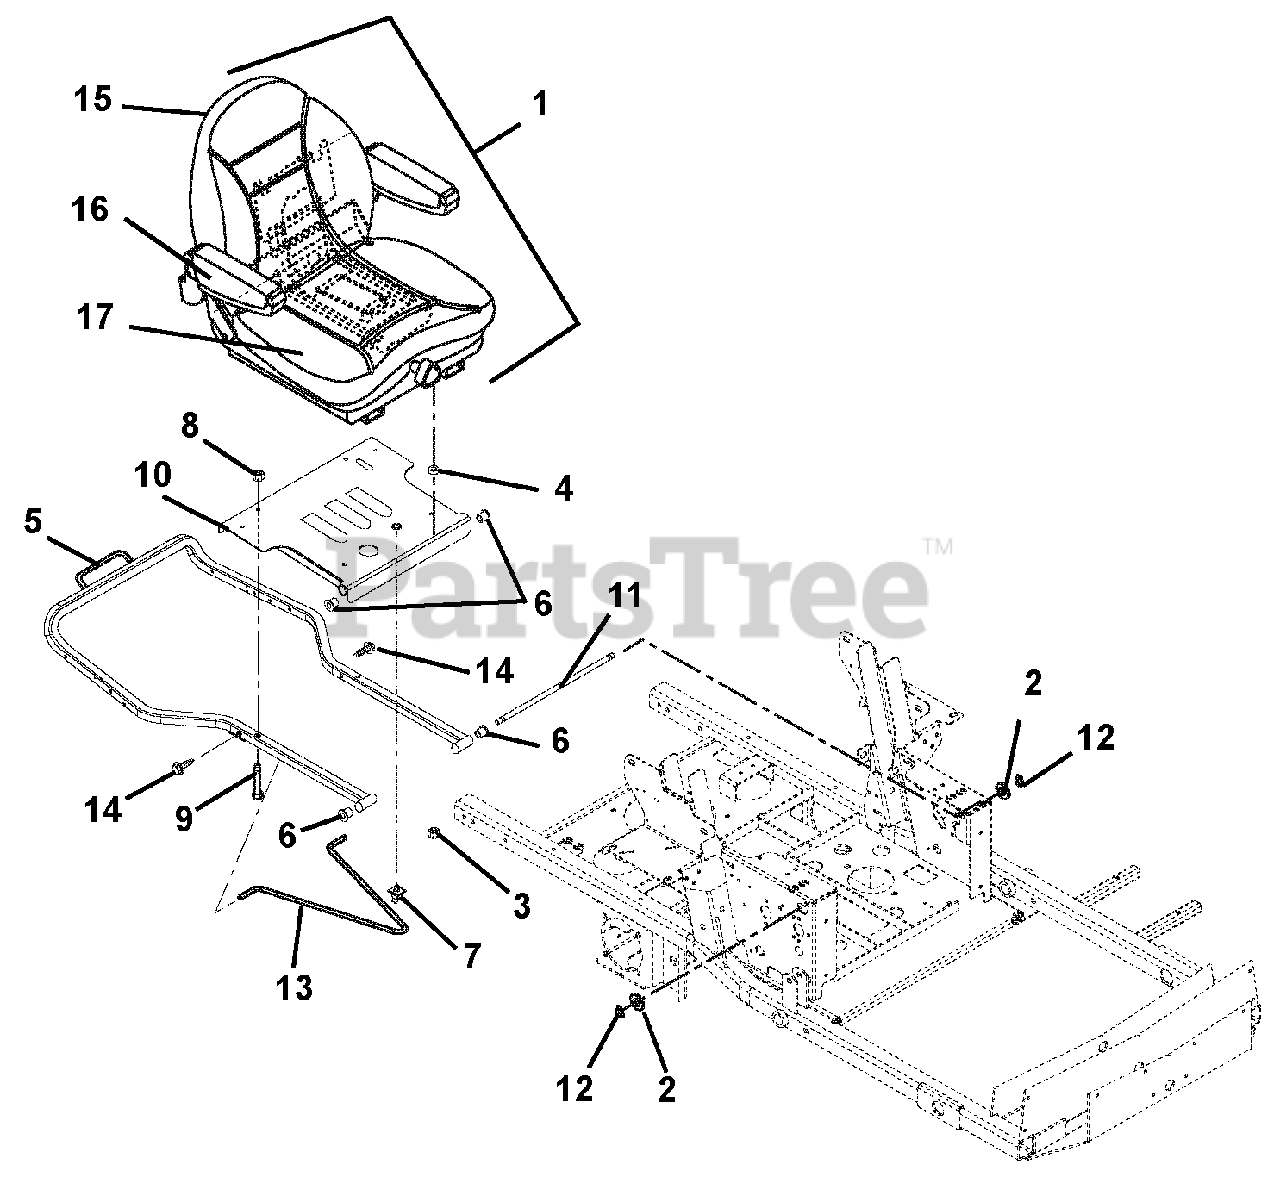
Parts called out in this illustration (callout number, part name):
1	Seat, Suspension
2	Washer, Flat Steel .531 x 1.06 x .095
3	Nut, Locking Top Flange .31-18
4	Bushing, Sleeve .377 x .624 x .235
5	Weldment, Hood Frame
6	Bushing-Flange .515 x .750 x .745 x 1.00
8	Nut, Locking Top Flange .38-16
9	Bolt, Rib Neck .38-16 x 1.50
10	Weldment, Seat Pivot Plate
11	Rod, Seat Frame Pivot
12	Ring, Retaining External .500 x .050
13	Rod, Prop
14	Screw, Tapping .25-20 x .50 Hex Washer Head
15	Kit, Back Cushion
16	Kit, Armrest
17	Kit, Seat Cushion
